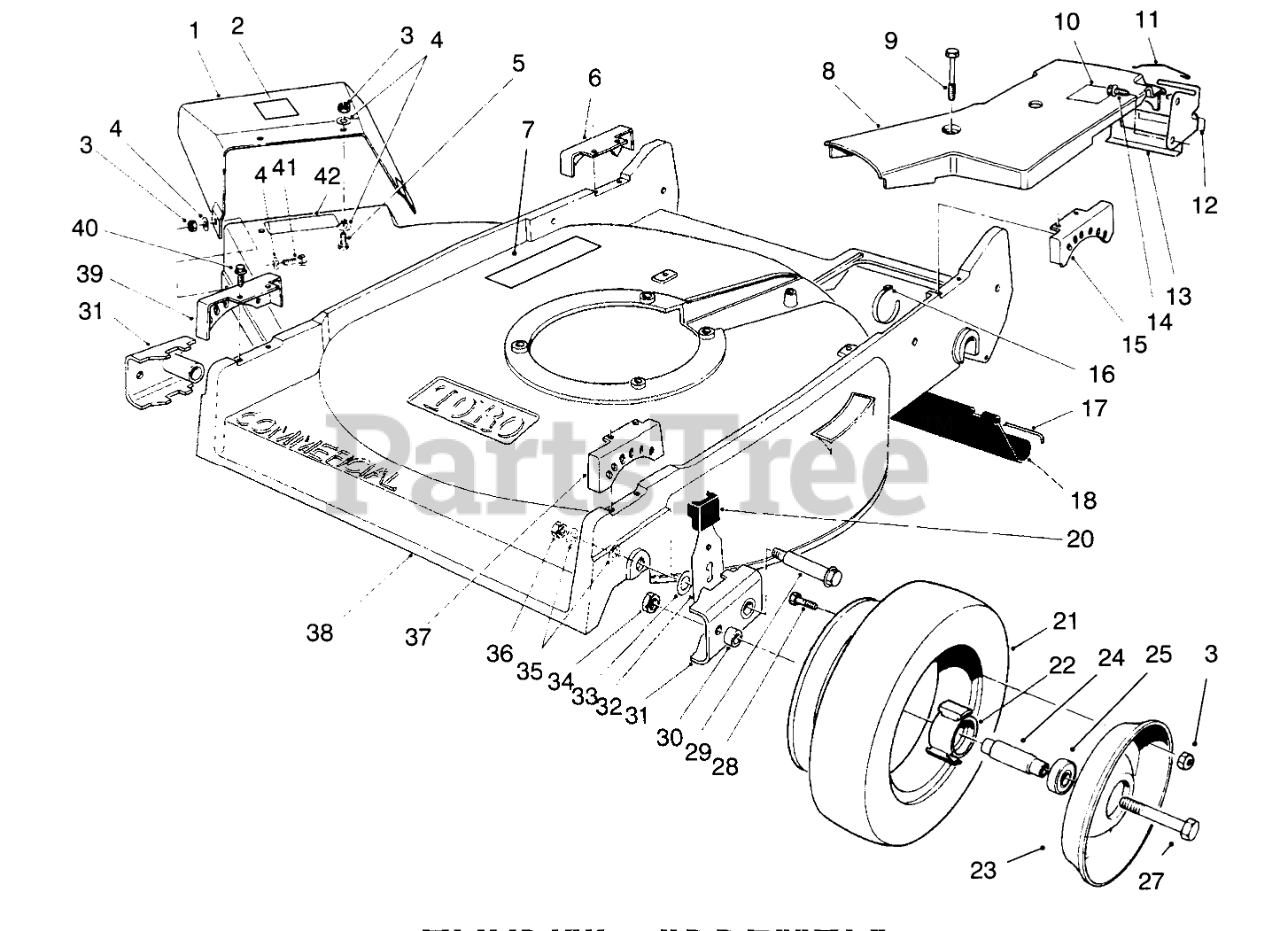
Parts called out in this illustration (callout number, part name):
1	Assembly-Deflector (Incl. Ref. #2)
2	DECAL-DANGER
3	NUT-LOCK, NI
4	WASHER-FLAT
5	SCREW-HH
6	QUADRANT-REAR, RH
7	DECAL-DANGER
8	COVER-BELT
9	SCREW-HHFTF
10	DECAL-GREASE
11	RETAINER-CABLE
12	DECAL-POSITION, GEAR
13	BRACKET-ADJUSTMENT, TRACTION
14	SCREW-HWHTF
15	QUADRANT-REAR, LH
16	TIE-CABLE
17	ROD-SHIELD
18	SHIELD-TRAILING
20	KNOB-ARM
22	HUB-BEARING
23	Wheel-Half
24	SPACER-BEARING
25	BEARING-WHEEL
27	SCREW-HH
28	SCREW-HH
29	BOLT-WHEEL
30	SPACER-WHEEL
31	ARM-PIVOT, FRONT
32	FRONT SPRING ARM ASM
33	WASHER-THRUST
34	NUT-LOCK, CONE
35	WASHER
36	NUT-LOCK
37	QUADRANT-FRONT, LH
38	Housing-Commercial (Incl. Ref. #42)
39	QUADRANT-FRONT, RH
40	SCREW-HWHTF
41	SCREW-HH
42	DECAL - WARNING
